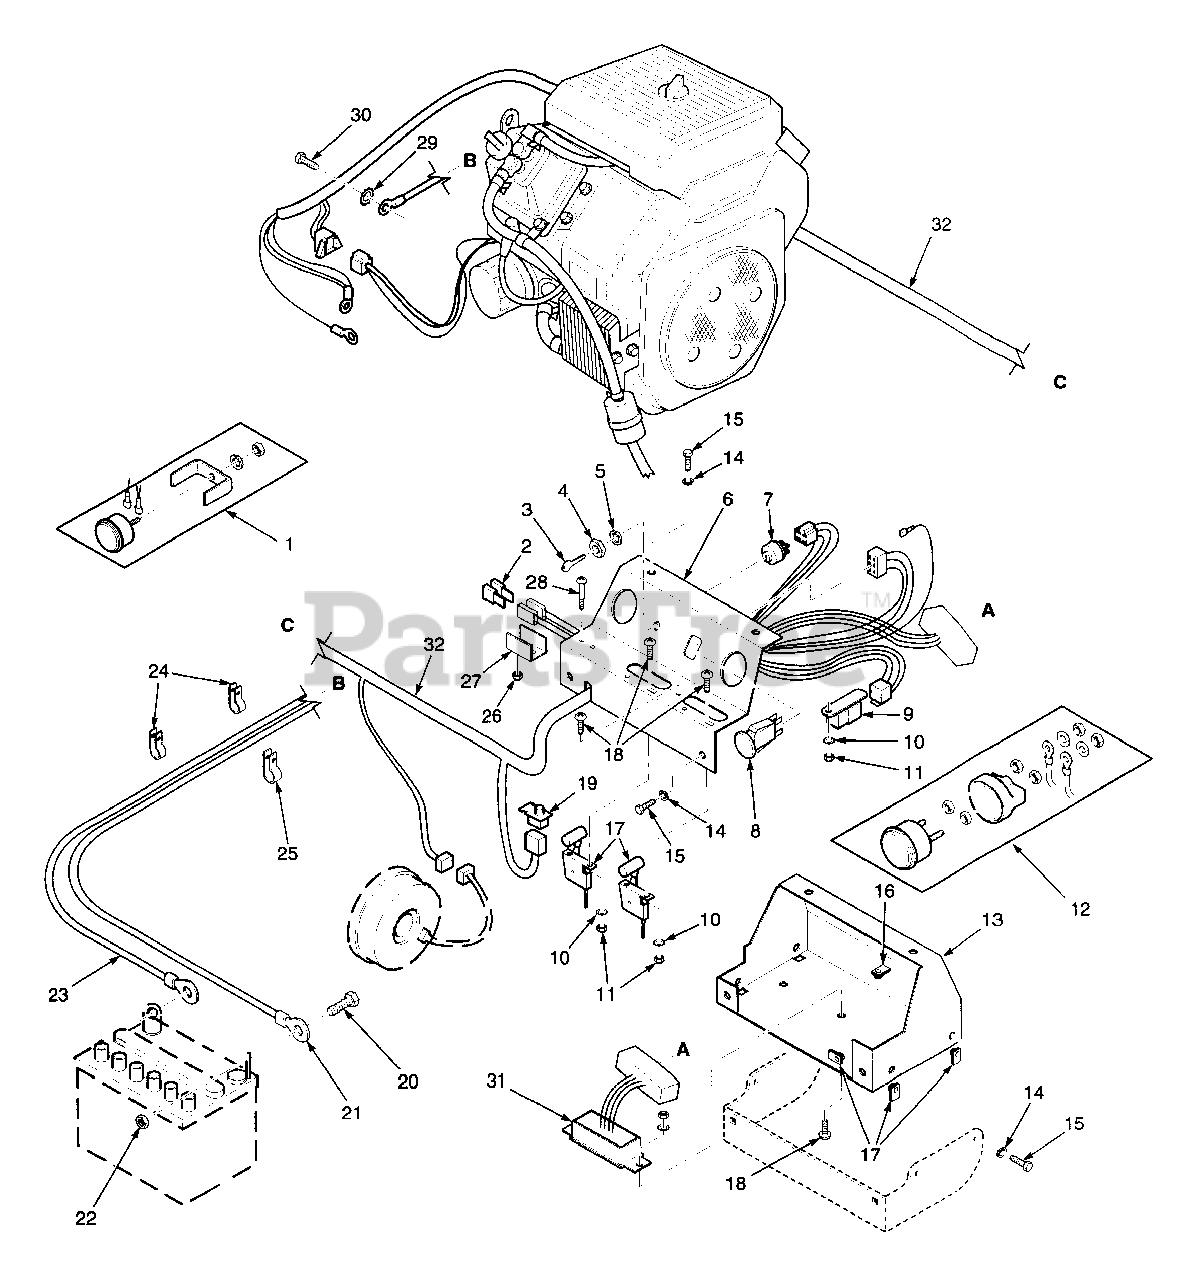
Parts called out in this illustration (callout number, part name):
1	Hour Meter
2	Fuse, 20 AMP
3	Key & Ring Assembly
4	Nut, Hex 5/8-32
5	Lockwasher, 5/8" Internal
6	Instrument Panel, Top
7	Key Switch
8	Switch, PTO
9	Relay
10	Lockwasher, #10 External Tooth
11	Nut, Hex #10-32
12	Ammeter
13	Base, Instrument Panel
14	Lockwasher, 1/4"
15	Bolt, Hex Head 1/4-20 x 3/4"
16	U-Nut, 1/4-20
17	Throttle And Choke Controls
18	Screw, Phillips Washer Head #10-32 x 1/2"
19	Switch, Interlock-Seat
20	Bolt, Hex Head 1/4-20 x 1/2"
21	Cable, Battery - Red 20"
22	Nut, Hex 1/4-20
23	Cable, Battery - Black
24	Clamp, Cable 1/2" ID.
25	Clamp, Cable 3/4" ID.
26	Nut, Hex Elastic Stop #10-32
27	Bracket, Fuse Holder
28	Screw, Phillips Washer Head #10-32 x 1-1/2"
29	Lockwasher, 5/16" External Tooth
30	Bolt, Hex Head M8-1.25 x 20
31	Electronic Module
32	Wire Harness, STT
